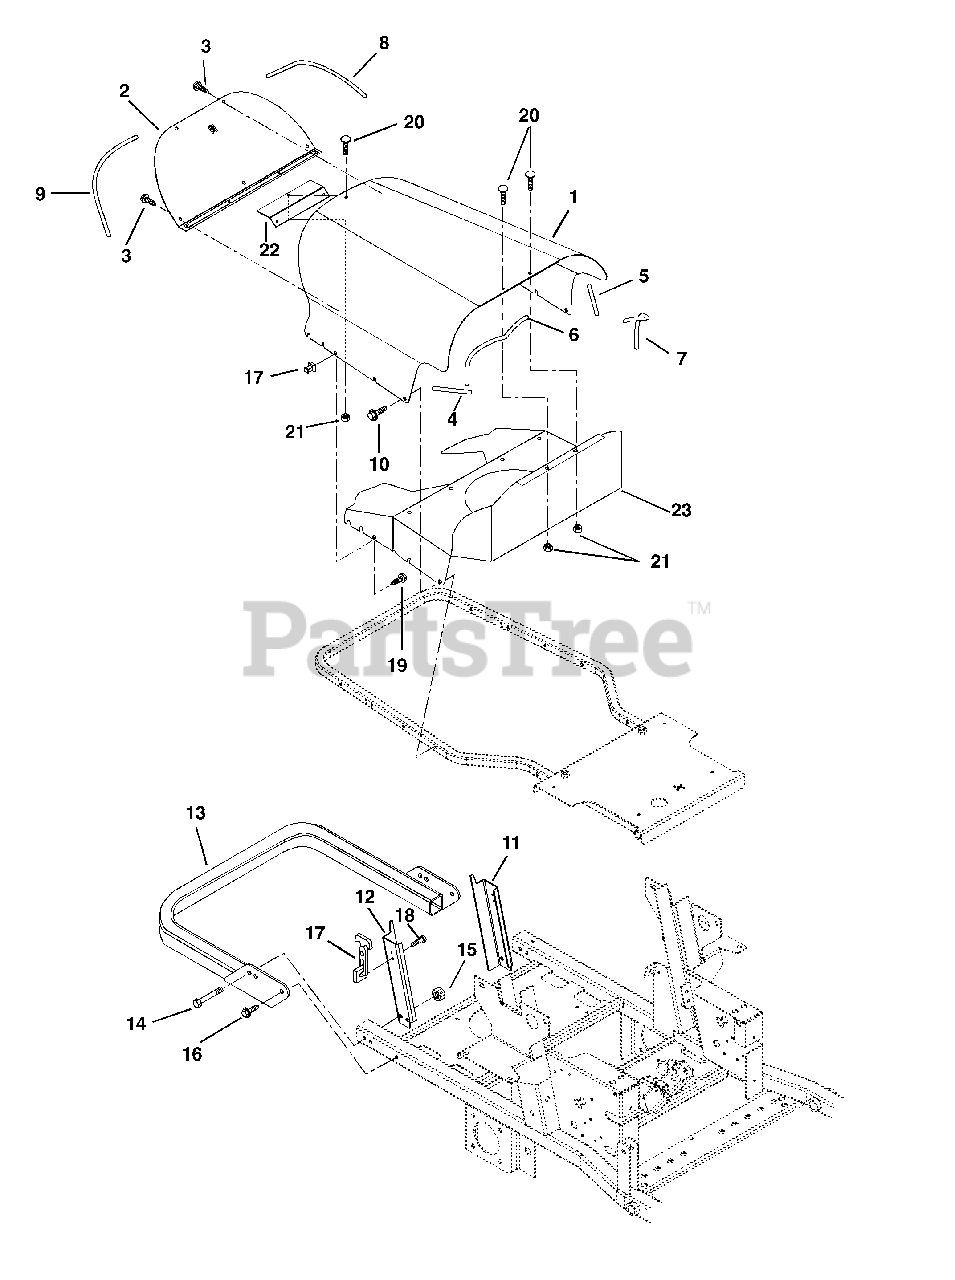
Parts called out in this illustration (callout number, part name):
1	Hood
2	Screen-Hood
3	Screw-Tapping .25 - 20 x .50 Hex Washer Head
4	Seal-Trim-Lok Bulk .06 Bubble
5	Seal-Trim-Lok Bulk .06 Bubble
6	Seal-Trim-Lok Bulk .06 Bubble
7	Seal-Trim-Lok Bulk .06 Bubble
8	Seal-Trim-Lok Bulk .06 Bubble
9	Seal-Trim-Lok Bulk .06 Bubble
10	Screw-Tapping .38 - 16 x .50 Hex Washer Head
11	Hood Support Left-Hand
12	Hood Support Right-Hand
13	Bumper-Rear
14	Bolt-Hex .38 - 16 x 3.00 Grade 5
14	Bolt-Hex .38 - 16 x 2.50 Grade 5
15	Nut-Locking-Center .38 - 16
16	Screw-Tapping .38 - 16 x .75 Hex Washer Head
17	Latch-Rubber
18	Screw-Machine 10 - 24 x .50 Hex Washer Head
19	Screw Machine 10 - 24 x .50 Hex Washer Head
20	Bolt-Round Head Square Shank .25 - 20 x .50 Grade 5
21	Nut-Locking-Nylon .25 - 20
22	Bracket-Screen Support
23	Weldment, Plenum
